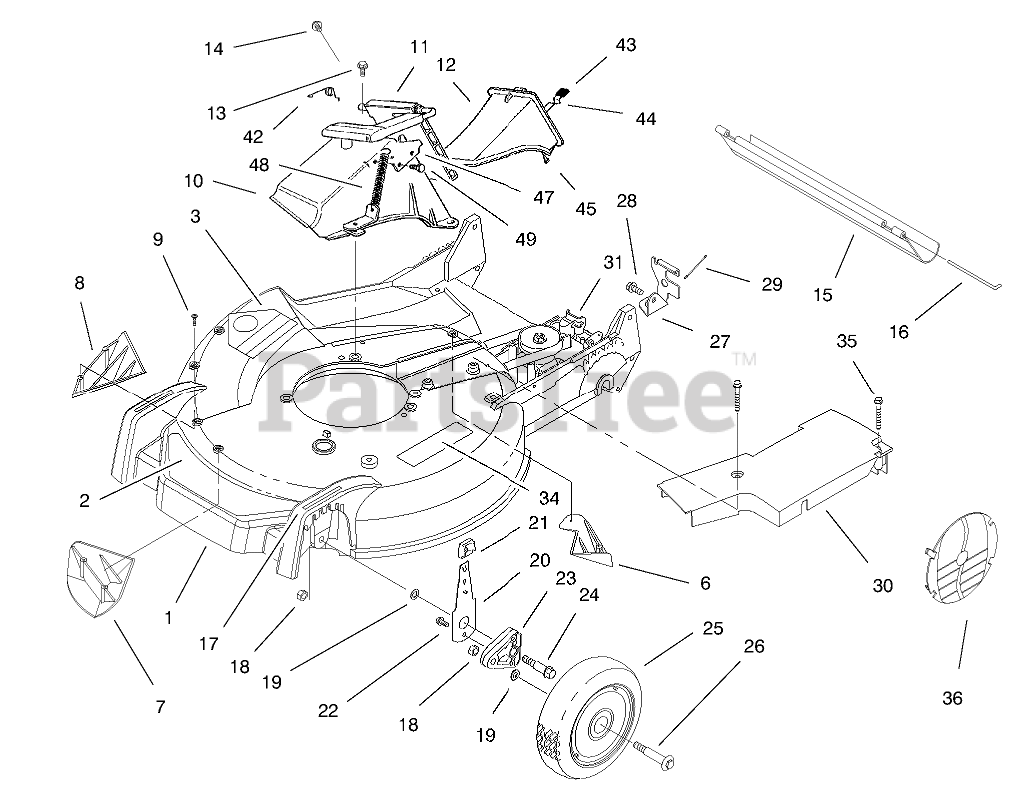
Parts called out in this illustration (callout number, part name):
1	Housing-21" (Incl. Ref. #3, 5-9 pg. 1, 34 pg. 2)
2	DECAL - DECK
3	DECAL-DANGER
6	KICKER-REAR
7	KICKER-FRONT
8	KICKER-RH
9	SCREW-PPH
10	DISCHARGE TUNNEL
11	DISCHARGE DOOR ASM
12	Plug-Discharge (Incl. Ref. #43-45)
13	SCREW-HWH
14	SCREW AND WASHER ASM
15	SHIELD-TRAILING
16	ROD-SHIELD
17	DECAL - HOC
18	NUT-LOCK
19	WASHER
20	FRONT SPRING ARM ASM
21	KNOB-ARM
22	SCREW-HWH
23	ARM-PIVOT, FRONT
24	BOLT-SHOULDER
25	WHEEL AND TIRE ASM
26	BOLT-WHEEL
27	Bracket-Adj. Trac
28	SCREW-HWHTF
29	RETAINER-CABLE
30	BELT COVER
31	GEARCASE ASM
34	DECAL-WARNING
35	SCREW-HHFTF
36	WHEEL COVER
41	BRACKET-SPRING
42	RETAINER-DOOR
43	GRIP-LATCH
44	LATCH-PLUG, DISCHARGE
45	RIVET-HEAD, FLAT
47	LATCH-PLATE
48	SPRING-DOOR
49	SCREW-PLASTITE
